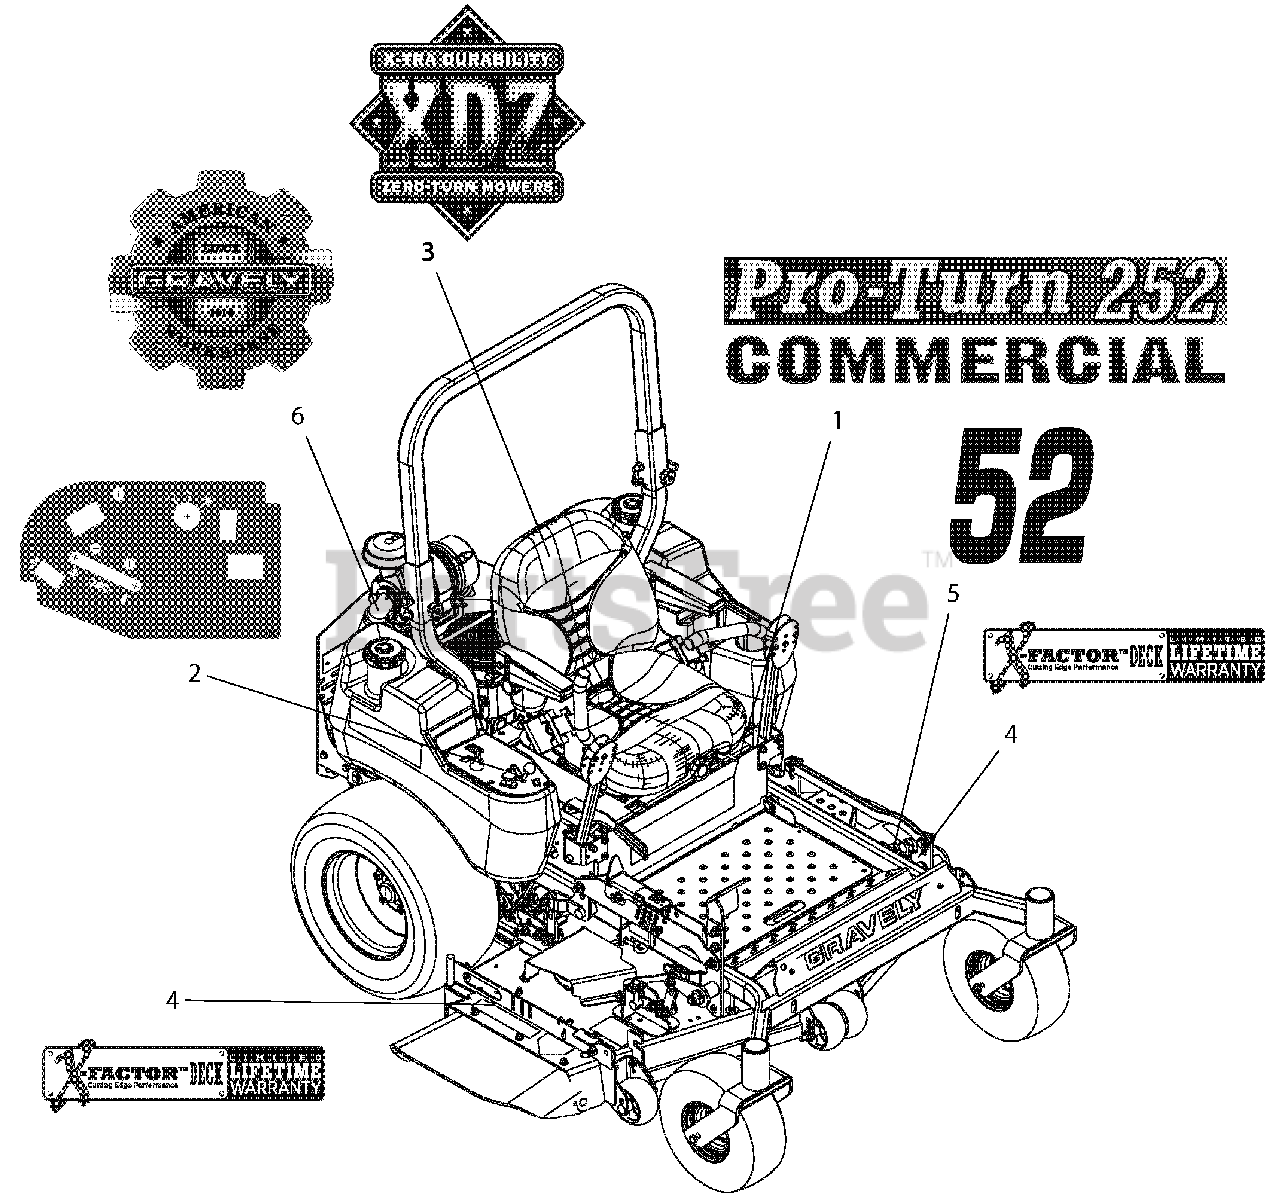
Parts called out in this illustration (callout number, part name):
1	DECAL, PROTURN 252
2	DECAL, CONTROL PANEL
3	DECAL, XDZ
4	DECAL, X-FACTOR DECK
5	DECAL, 52"
6	DECAL, GRAVELY HERITAGE-LARGE
